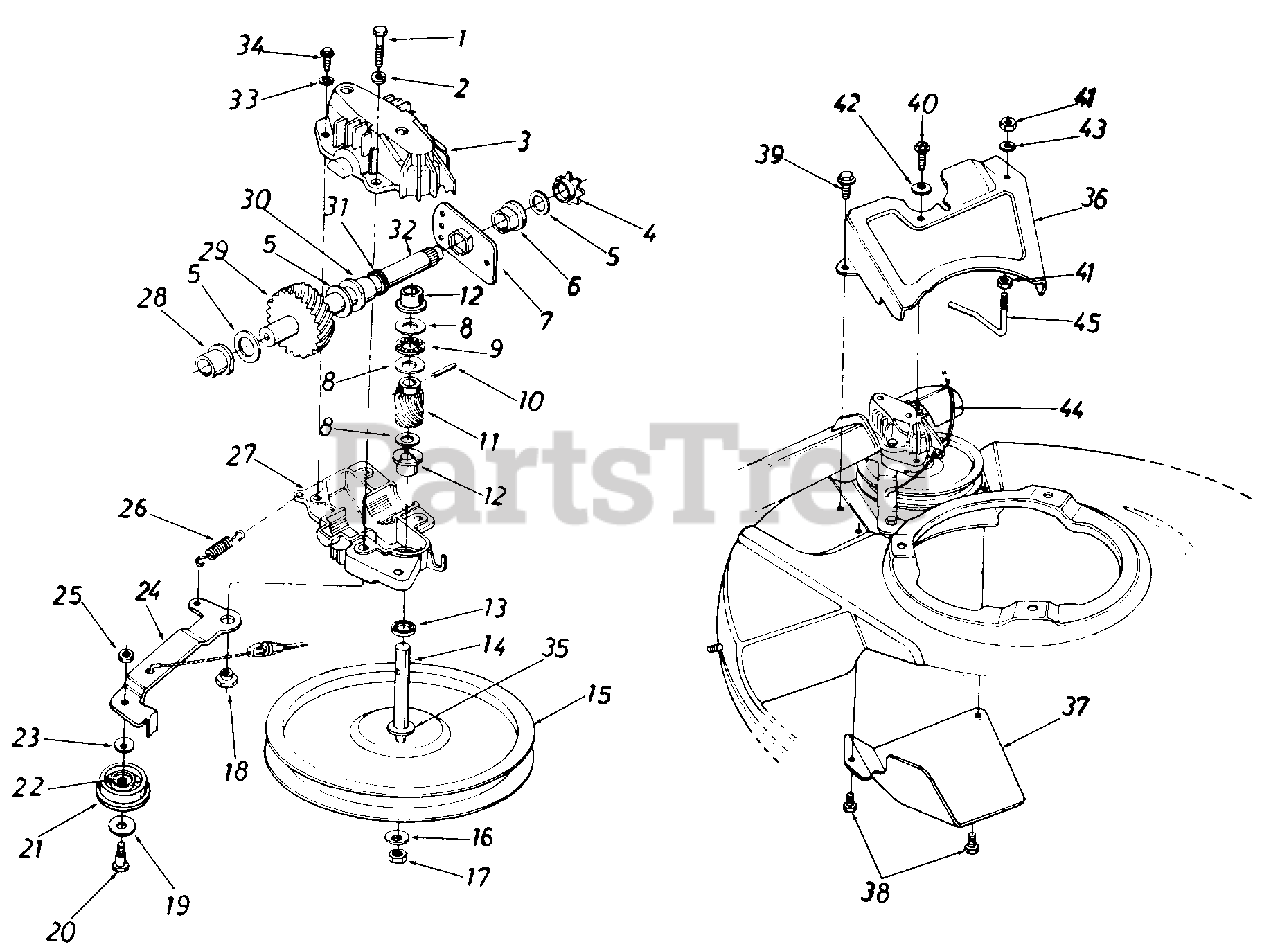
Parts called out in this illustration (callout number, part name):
1	Hex Bolt 1/4-20 x 1.25" Lg.
2	L-Wash. 1/4" I.D.
3	Upper Hsg. Half
4	#48 Sprocket 7 Tooth x 1/2 Pitch
5	Fl-Wash. 518" I.D. x .030
6	Hex Flange Brg. .631" I.D.
7	Hex Bearing Cup
8	Thrust Wash. .382" I.D. x .70" O.D.
9	Thrust Bearing .375" I.D. x .812" O.D.
10	Spring Pin Spir. 1/8" x .62" Heavy
11	11 Tooth Helical Gear
12	Flange Bearing
13	Oil Seal
14	Pulley-Transmission Shaft
15	Fl-Pulley 5.06" I.D.
16	Bell-Wash. .265" I.D. x .75"
17	Hex Nut 1/4-28 L.H. Thd.
18	Shld. Spacer .375" Dia. x .170
19	Fl-Wash. .390" I.D. x 1.0"
20	Shld. Bolt .375" Dia. x .40"
21	Fl-Idler Plastic 1.50" Dia.
22	Needle Brg. .375" x .31"
23	Bell-Wash. .265" I.D. x 75"
24	Idler Brk't. Ass'y.
25	Hex Patch L-Nut 1/4-28 Thd.
26	Extension Spring 1.12" Lg.
27	Lower Hsg. Half
28	Flange Bearing .566 Dia.
29	33 Tooth Helical Gear
30	Flange Bearing .629 Dia.
31	Oil Seal .625 Dia.
32	Gear Sprocket Shaft
33	L-Wash. #10 I.D.
34	Hex B-Tap Scr. #10 x .62"
35	Hex Washer .26" x .88"
36	Transmission Belt Guard
39	Hex AB-Tap Scr. 1/4 x .50" Lg.
40	Hex B-Tap Scr. 1/4 x .62" Lg.
41	Hex Nut 1/4-20 Thd *
42	Bell-Wash. .265" I.D. x 75"
43	L-Wash. 1/4" I.D.
44	S.P. Cable-48" Lg.
45	S.P. Belt Guard
